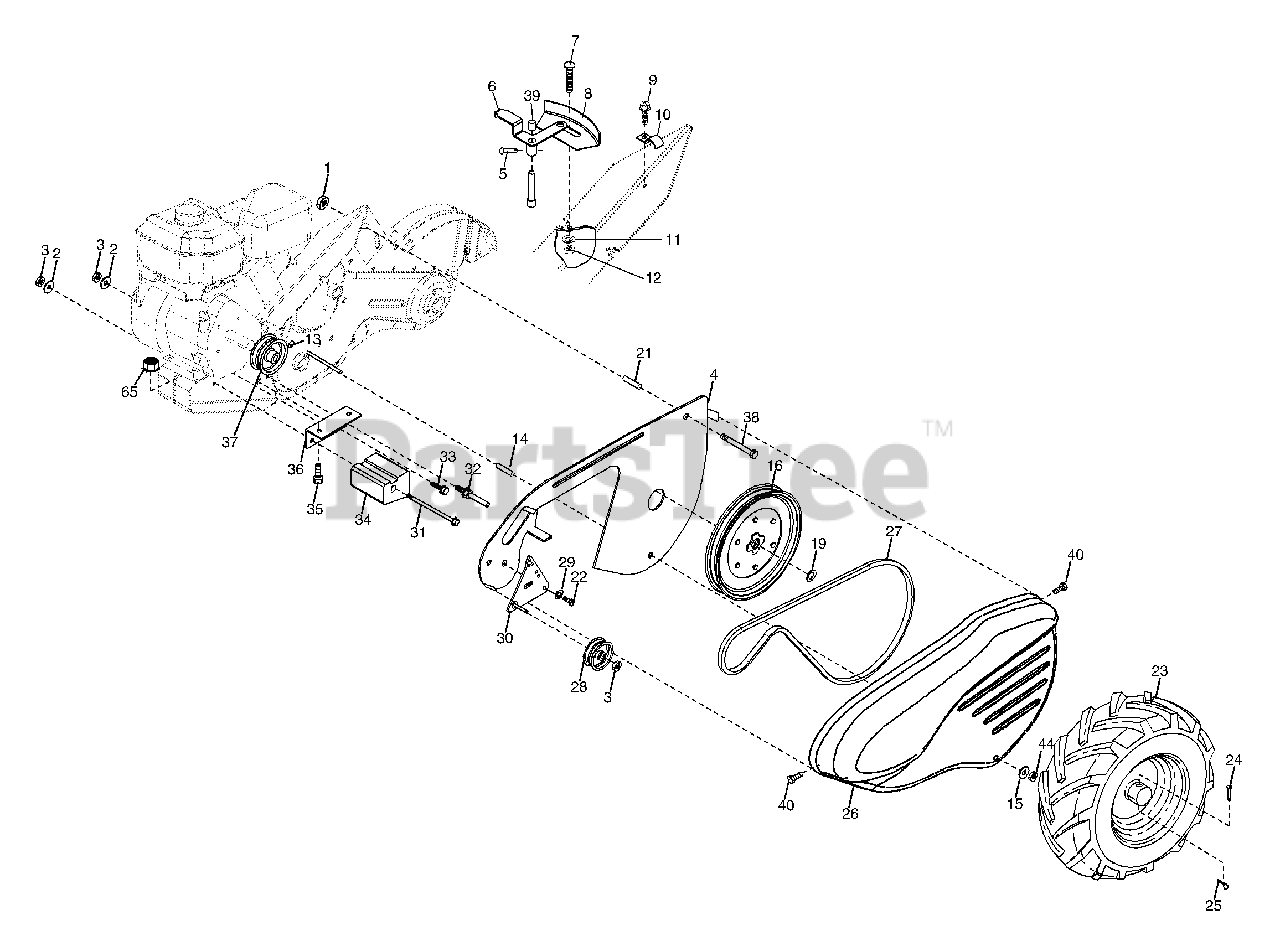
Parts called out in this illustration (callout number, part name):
1	Nut, Keps 5/16-18
2	Washer, Lock 3/8
3	Nut, Hex 3/8-16
4	Shield, Inner Belt Guard RT
5	Screw, Shift Lever
6	Lever, Shift
7	Bolt, Carriage 1/4-20 x 1/2 Gr. 5
8	Plate, Shift Indicator
9	Screw, Hex, Washer Head, Slotted #10-24 x 1/2
10	Clip
11	Washer, Lock 1/4
12	Nut, Hex 1/4-20
13	Screw, Set, Hex 5/16-18 x 3/8
14	Spacer, Split 0.327 x 0.42 x 1.220
15	Washer 11/32 x 11/16 x 16 Ga.
16	Sheave, Transmission
19	Retainer, Ring
21	Spacer, Split 0.327 x 0.42 x 2.09
22	Bolt, Fin Hex 5/16-24 UNF x 1/2
23	Tire
23	Rim
23	Tire Valve
24	Rivet, Drilled
25	Clip, Hairpin
27	Belt, V
28	Pulley, Idler
29	Ring, Klip
30	Bracket, Idler
31	Bolt, Hex 5/16-16 x 12
32	Shaft, Idler Arm
33	Bolt, Hex 3/8-16 x 1
34	Counterweight, L. H.
35	Bolt, Hex 5/16-18 x 1-3/4
36	Bracket, Reinforcement, L. H.
37	Sheave, Engine
38	Bolt, Fin Hex 5/16-18 unc x 2-3/4
39	Cap, Plunger Blk
40	Screw Hex Wsh Slt #10-24 x 1/2
44	Nut Lock Hex w/Ins 5/16-18 unc PL
65	Nut Lock Hex Flange
